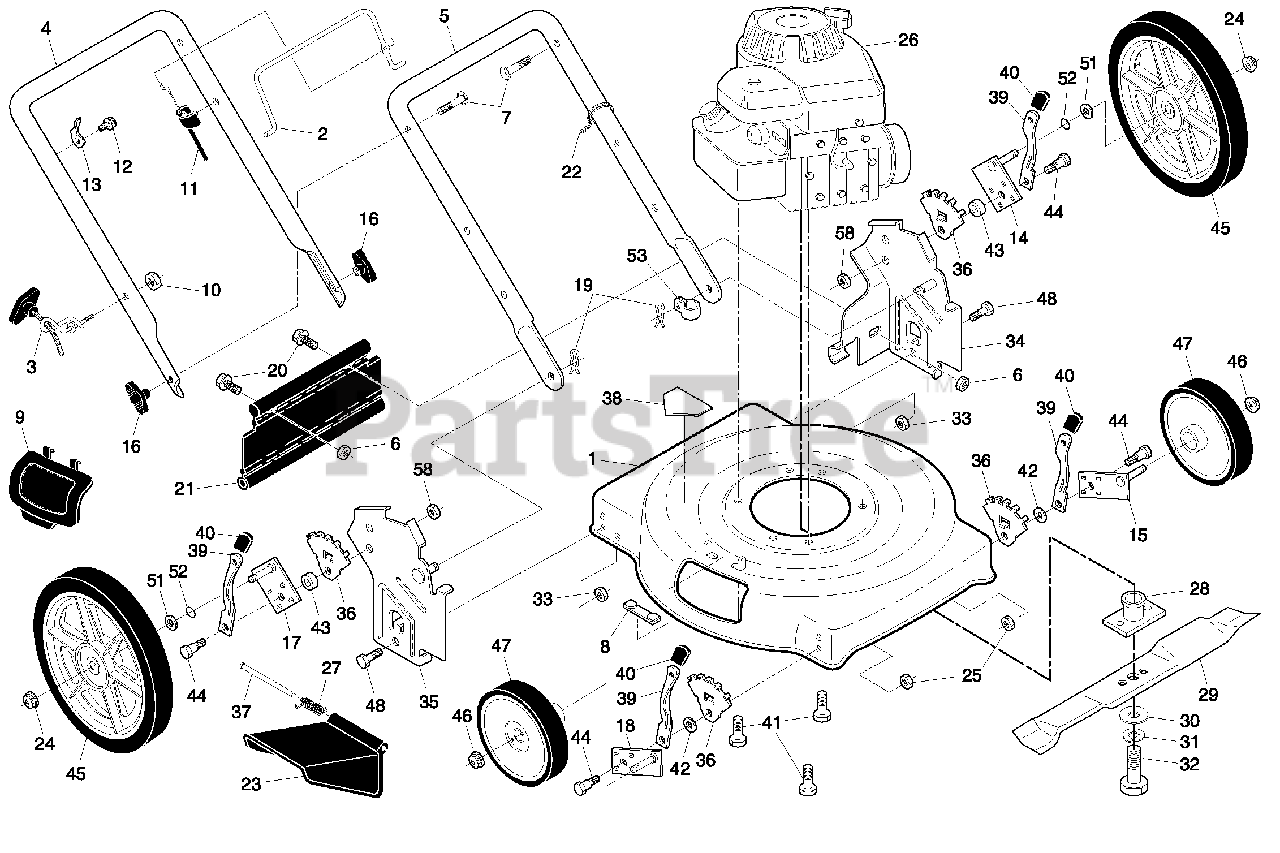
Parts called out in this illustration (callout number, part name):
1	Lawn Mower Housing
2	Control Bar
3	Rope Guide
4	Upper Handle
5	Lower Handle
6	Locknut, Hex 1/4-20
7	Handle Bolt 5/16-18
8	Clip, Closeout
9	Mulcher Plate
10	Nut, Hex 1/4-20
11	Engine Zone Control Cable
12	Hex Washer Head Screw #10-24 x 1/2
13	Up-Stop Bracket
14	Axle Arm Assembly, Rear, LH
15	Axle Arm Assembly, Front, LH
16	Knob, Handle
17	Axle Arm Assembly, Rear, RH
18	Axle Arm Assembly, Front, RH
19	Hairpin Cotter
20	Screw, Hex Cap Head 1/4-20
21	Rear Defl ector
22	Wire Tie
23	Discharge Guard
24	Nut, Hex, Flangelock 3/8-16
25	Nut, Hex, Flangelock 5/16-18
27	Torsion Spring
28	Blade Adapter
29	22" Blade
30	Hardened Washer
31	Helical Lockwasher 3/8
32	Screw, Hex Head, Grade 8, 3/8-24 x 1-3/8
33	Nut, Hex, Nylock 5/16-18
34	Handle Bracket, LH
35	Handle Bracket, RH
36	Wheel Bracket Adjuster
37	Hinge Rod
38	Danger Decal
39	Selector Spring
40	Selector Knob
41	Screw, Hex Head, Threaded, Rolled 3/8-16 x 1
42	Washer, Step
43	Spacer
44	Shoulder Bolt 5/16-18
45	Wheel & Tire Assembly, Rear, 12"
46	Nut, Hex, Flangelock 3/8-16
47	Wheel & Tire Assembly, Front, 8"
48	Bolt, Hex Head 5/16-18
51	Washer, Flat 3/8
52	O-Ring
53	Clip, Cable
58	Nut, Hex
58	Operator's Manual, English
58	Operator's Manual, Spanish
58	Repair Parts Manual
